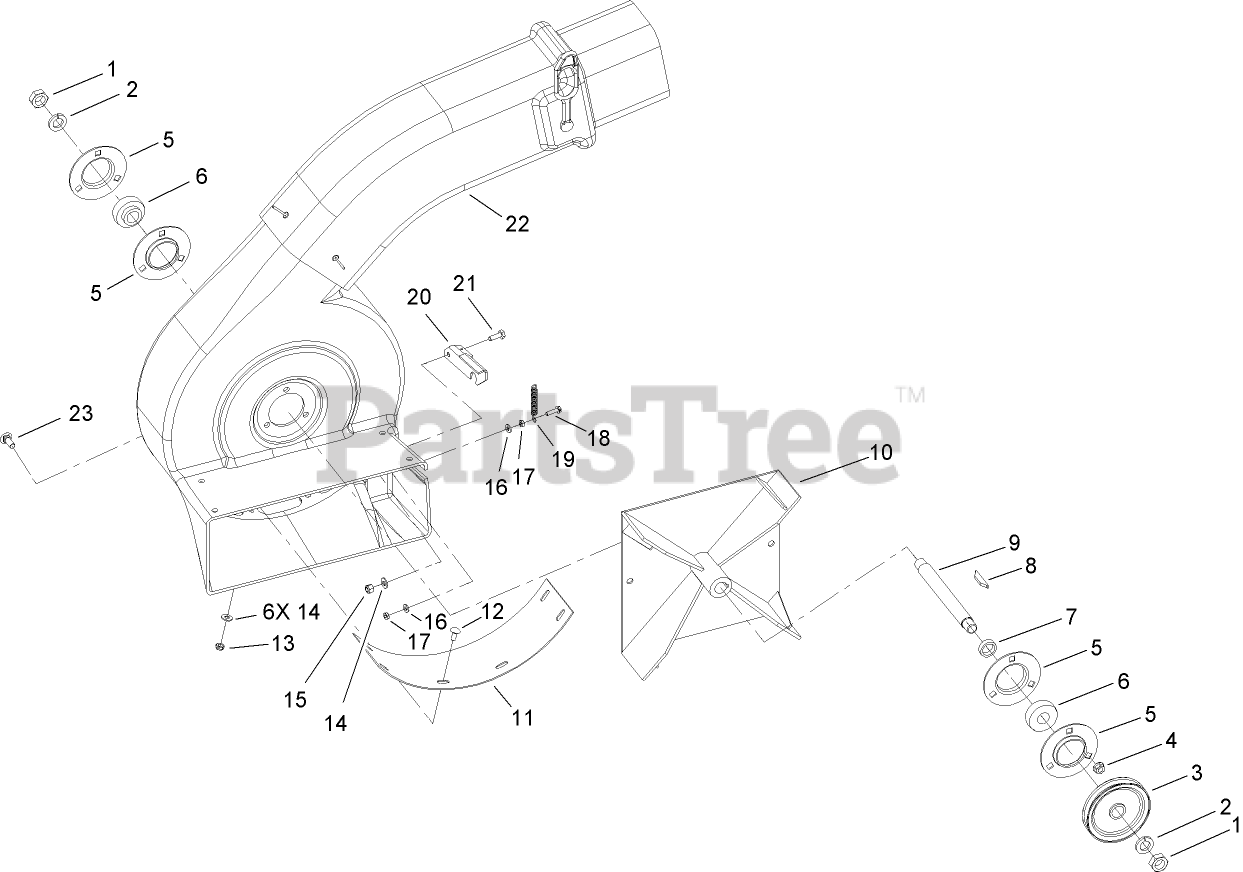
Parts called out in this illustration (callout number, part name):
1	NUT-JAM
2	WASHER-LOCK
3	PULLEY-BLOWER
4	NUT-HF
5	FLANGE
6	BEARING-BALL
7	SPACER
9	SHAFT-BLOWER
10	IMPELLER ASM
11	COVER-BLOWER, BOTTOM
12	SCREW-CARR
13	NUT-LOCK, NI
14	WASHER-FLAT
15	NUT-LOCK, NI
16	WASHER-FLAT
17	NUT-HEX
18	SCREW-HWH
19	SPRING-EXTENSION
20	LATCH-BLOWER
21	SCREW-HH
22	BLOWER HOUSING ASM
23	SCREW-CARR
